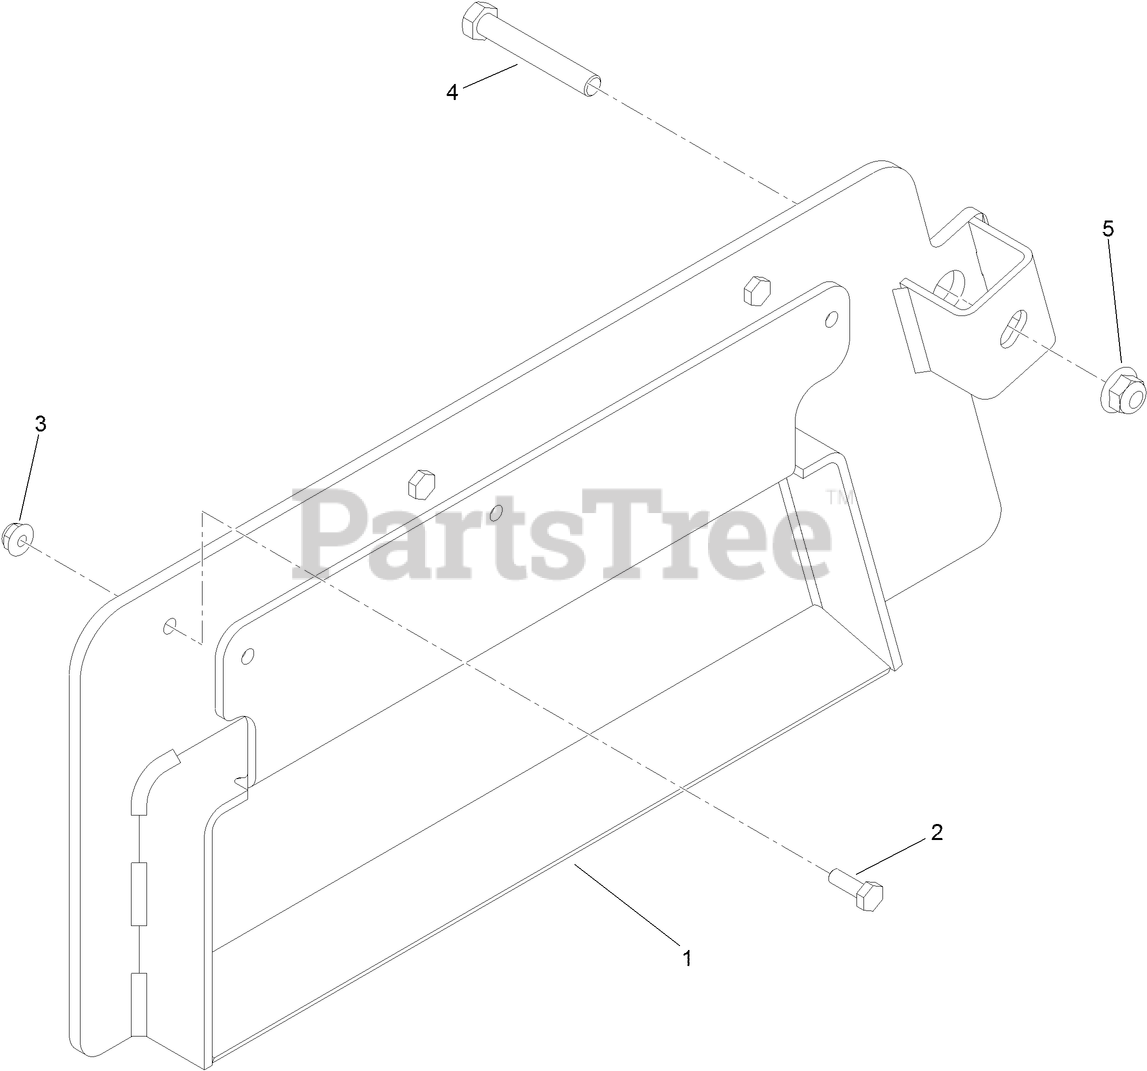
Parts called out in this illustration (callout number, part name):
1	ADAPTER-BAGGER
2	SCREW-HH
3	NUT-HF
4	SCREW-HH
5	NUT-HF, NI
